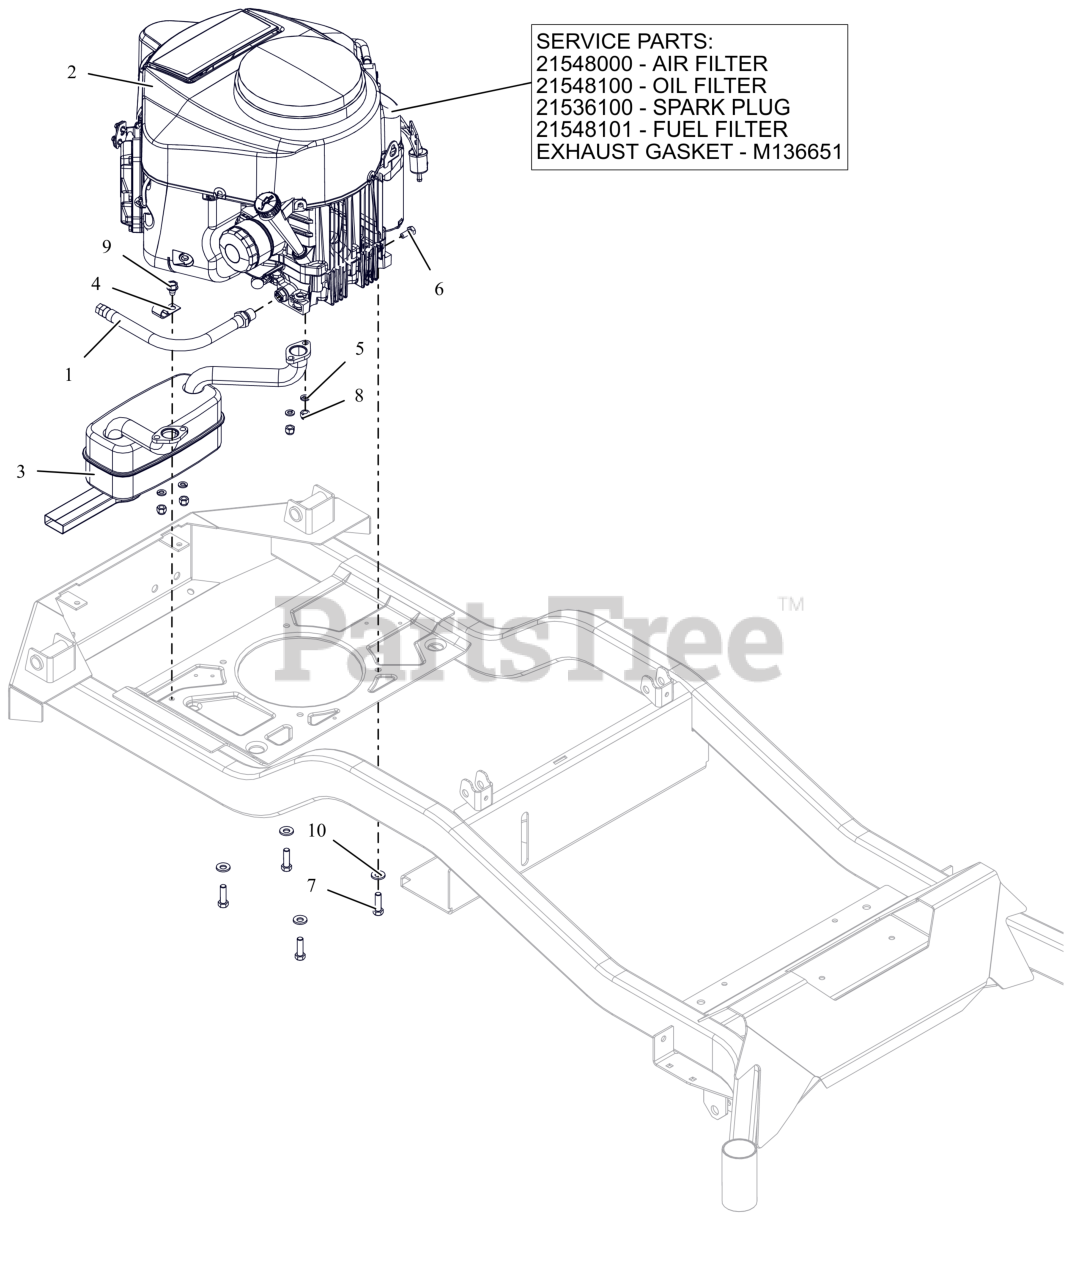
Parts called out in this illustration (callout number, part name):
1	HOSE, OIL DRAIN
2	ENGINE, KAWASAKI FR691 23HP
2	AIR FILTER, KAWASAKI FR
2	OIL FILTER, KAWASAKI FR
2	PLUG, SPARK
2	FUEL FILTER-KAWASAKI FR
2	GASKET, MUFFLER #
3	MUFFLER, KAWASAKI
4	J-CLAMP
5	WSHR,LK-REG .312X.078 ZCC
6	BLT, HEX M8-1.25X20 G8.8 ZCC
7	BLT, HEX .38-16X1.25 G5 ZCC NT
8	NUT, LK-CTR-JAM M8-1.25 GR8.8 ZC120
9	SCR,TAP .375-16X.50 HWH TR ZCC
10	WASHER, 3/8" SPRING DISC
